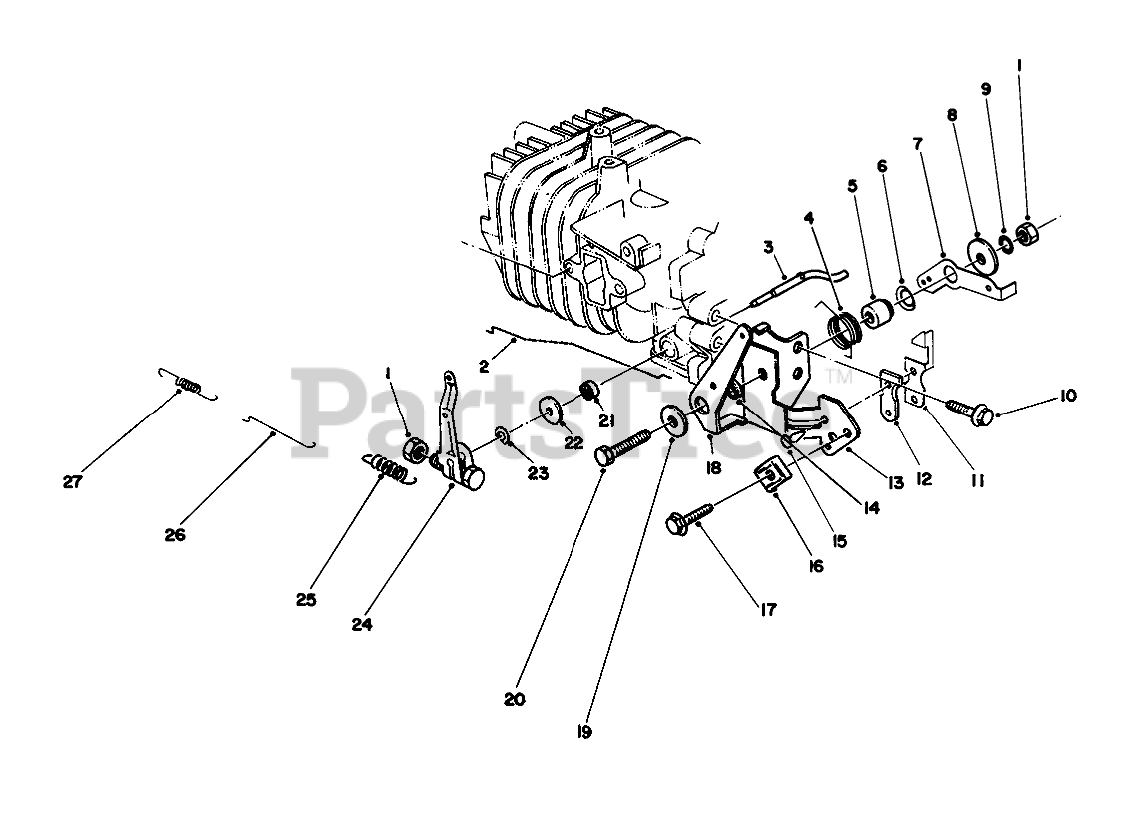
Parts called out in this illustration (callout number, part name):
2	CHOKE ROD
3	Shaft-Govemor
4	SPRING-CHOKE LEVER
5	Gov Lever Spacer
6	Washer-Gov. Spring Lever
7	LEVER-SPRING, GOVERNOR
8	WASHER
9	LOCKWASHER
11	TERMINAL-KILL SWITCH
12	INSULATOR-KILL SWITCH
13	BRACKET-THROTTLE, CONTROL
14	SPACER-CHOKE LEVER
15	KILL SWITCH RIVET
16	CLAMP
18	LEVER-CONTROL, CHOKE
19	WASHER
21	SEAL-OIL
22	WASHER
23	E-RING
24	GOVERNOR ARM
25	SPRING-GOVERNOR
26	ROD-CARBURETOR
27	SPRING
